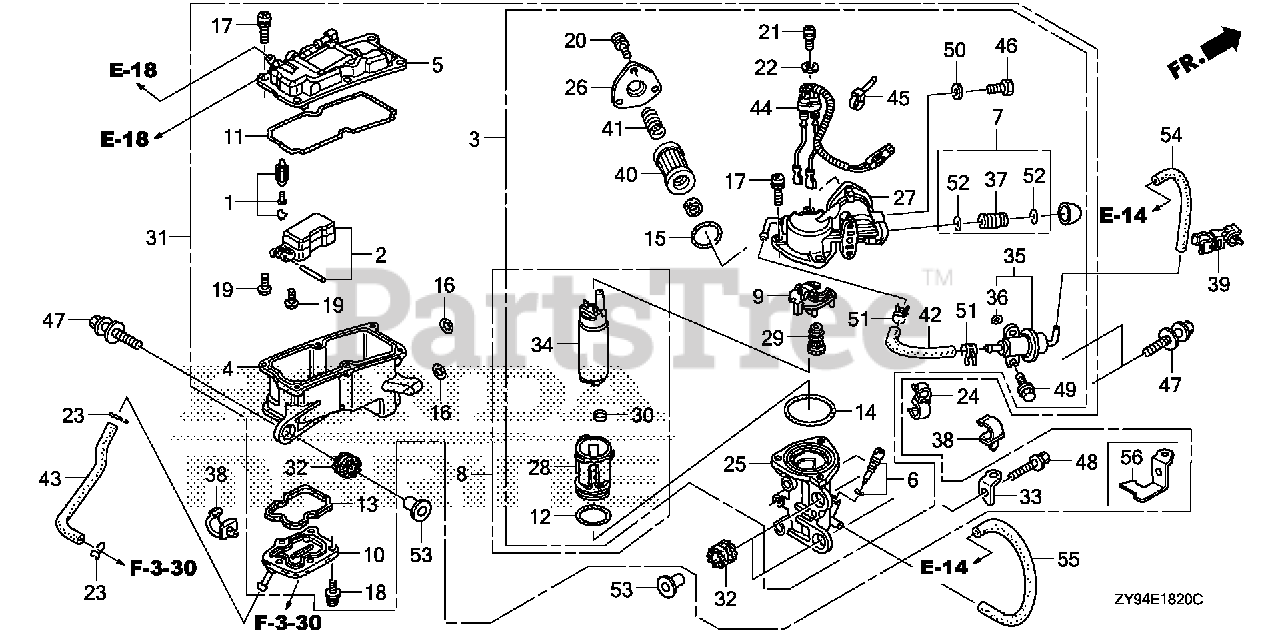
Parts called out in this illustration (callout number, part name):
1	VALVE SET, FLOAT
3	PUMP UNIT, FUEL (A) (MSDS)
6	SCREW SET, DRAIN (CARBURETOR NO.)
8	PUMP UNIT, FUEL (B) (MSDS)
9	HOLDER
10	COVER, WATER JACKET
17	SCREW-WASHER
18	SCREW-WASHER
19	SCREW, PAN
20	SCREW-WASHER
21	SCREW, WASHER
22	WASHER, PLAIN
23	CLIP, TUBE (ENGINE NO.)
24	CLAMP, CHECK VALVE
25	CASE, PUMP
26	COVER B, PUMP
27	COVER, PUMP (A)
29	INSULATOR
31	SEPARATOR ASSY., VAPOR
32	GROMMET, VAPOR SEPARATOR
33	STAY, FUEL TUBE
34	PUMP UNIT, FUEL (MSDS)
35	REGULATOR ASSY., PRESSURE
36	O-RING, PRESSURE REGULATOR
37	JOINT, FUEL PIPE
38	CLAMP B, FUEL TUBE
39	CLAMP D, FUEL TUBE
40	SCREEN, FUEL STRAINER
41	SPRING, COMPRESSION
42	HOSE, PRESSURE REGULATOR RETURN
43	TUBE A, WATER
46	BOLT, SEALING (6MM)
47	BOLT-WASHER (8X35)
48	BOLT, FLANGE (6X25)
49	BOLT, FLANGE (6X14)
50	WASHER, SEALING (6MM)
51	CLAMP, TUBE (D10.7)
52	O-RING (7.8X1.9) (ARAI)
53	COLLAR (8.5X14.5)
54	BULK HOSE, FUEL (3.5X3000) (3.5X120)
55	BULK HOSE, VINYL (5X9X1000) (5X9X240)
56	STAY, FUEL TUBE
